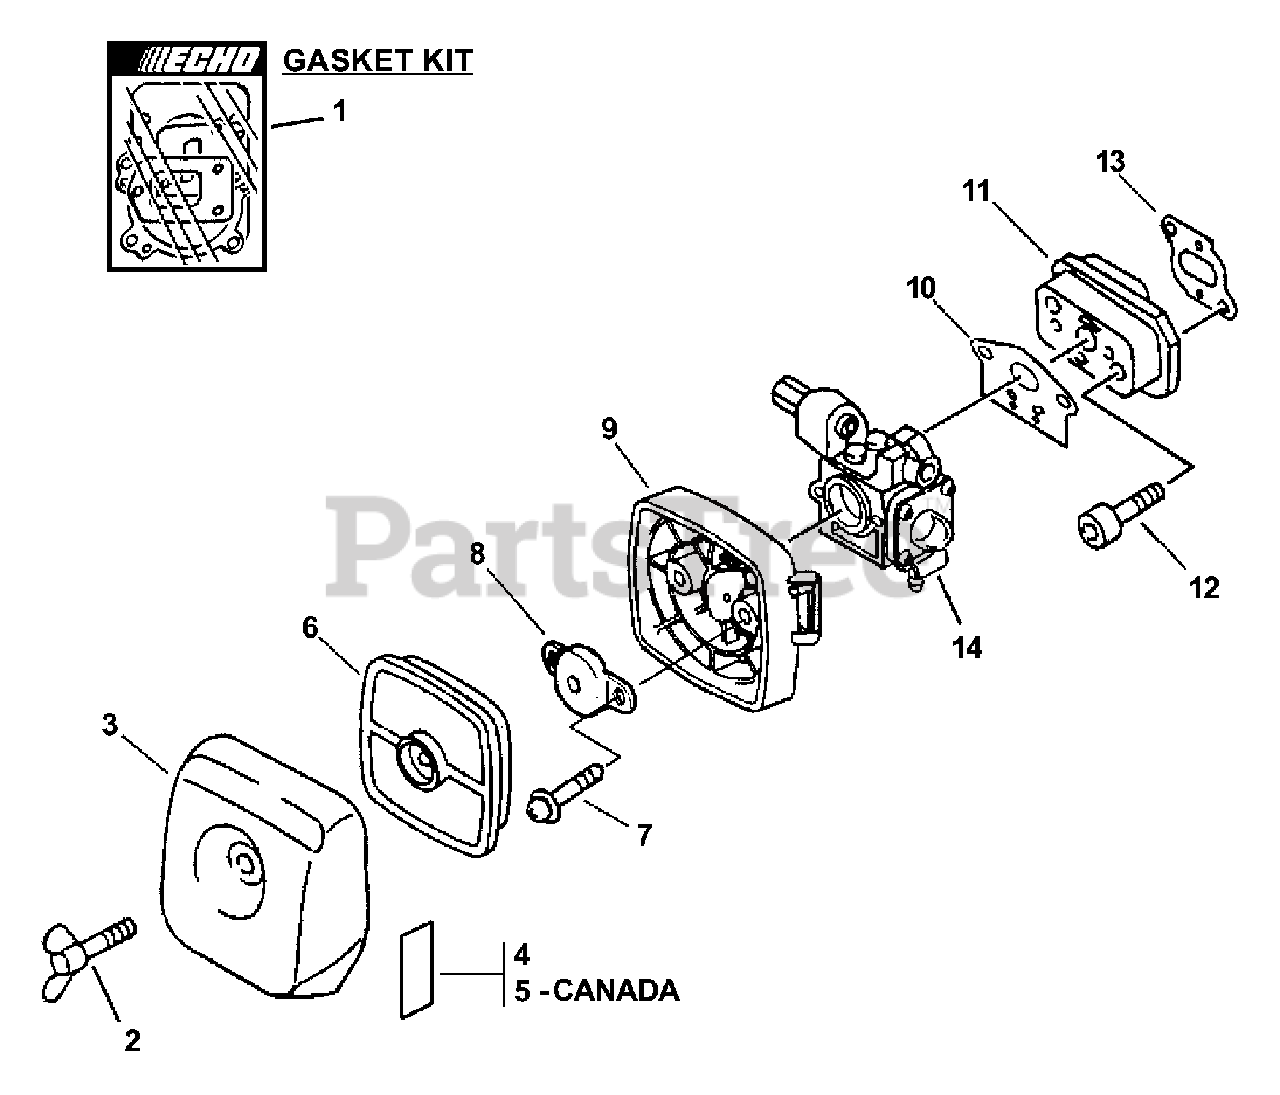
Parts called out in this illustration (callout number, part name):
1	GASKET KIT
2	THUMBSCREW
3	COVER, AIR FILTER - BLACK
4	LABEL - CHOKE
5	LABEL - CHOKE
6	FILTER, AIR - SINGLE LAYER
7	SCREW - 5X60
8	PLATE, PREVENT
9	CASE, AIR FILTER - BLACK
10	GASKET, INTAKE
11	INSULATOR, INTAKE
12	SCREW - 5X25
13	GASKET, INTAKE
14	CARBURETOR
